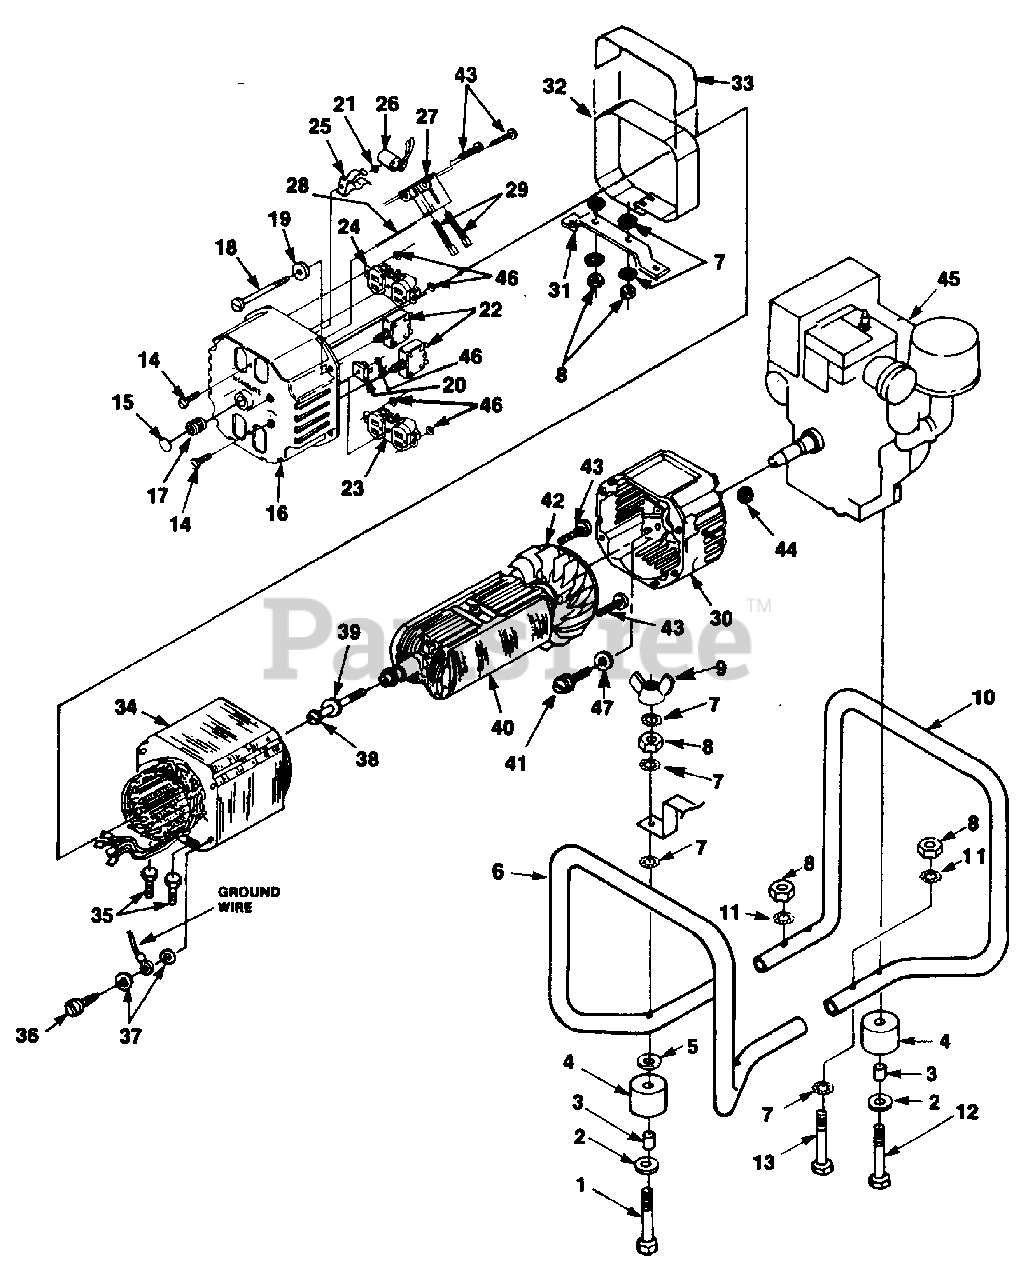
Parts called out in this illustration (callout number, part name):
2	WASHER- Flat (5/16")
3	SPACER- Foot
5	WASHER- Flat (5/16")
6	MEMBER- Frame
7	WASHER- Lock
8	NUT- Hex (5/16-18)
9	NUT- Wing
10	MEMBER- Frame
11	WASHER- Lock
12	SCREW- (5/16 x 31/4")
14	SCREW- Mach. pan hd.
15	PLUG- Expansion
16	BRUSH HEAD
17	BEARING- Needle
18	BOLT- Stator
19	WASHER- Flat
20	RECTIFIER
21	WASHER- Shaft retention
22	BREAKER- Circuit (20 amp.)
23	RECEPTACLE- (240 V) (Nema 6-20R)
24	RECEPTACLE-Duplex(Nema 5-15R)
25	CLIP-Spring cap
26	CAPACITOR
27	BRUSH HOLDER
28	PIN- Retaining
29	BRUSH
30	BELL- End
31	BRACKET- Generator support
32	WRAPPER- Stator
33	DECAL- Warning
35	SCREW- 5/16-18 x 3/4"
37	WASHER- Lock
38	BOLT- Rotor
39	WASHER
41	SCREW-(3/8-16 x 7/8")
42	FAN- Generator
43	SCREW- Pan hd.
44	NUT- Hex
45	ENGINE
46	WASHER- Shaft retention
47	WASHER- Lock (3/8")
